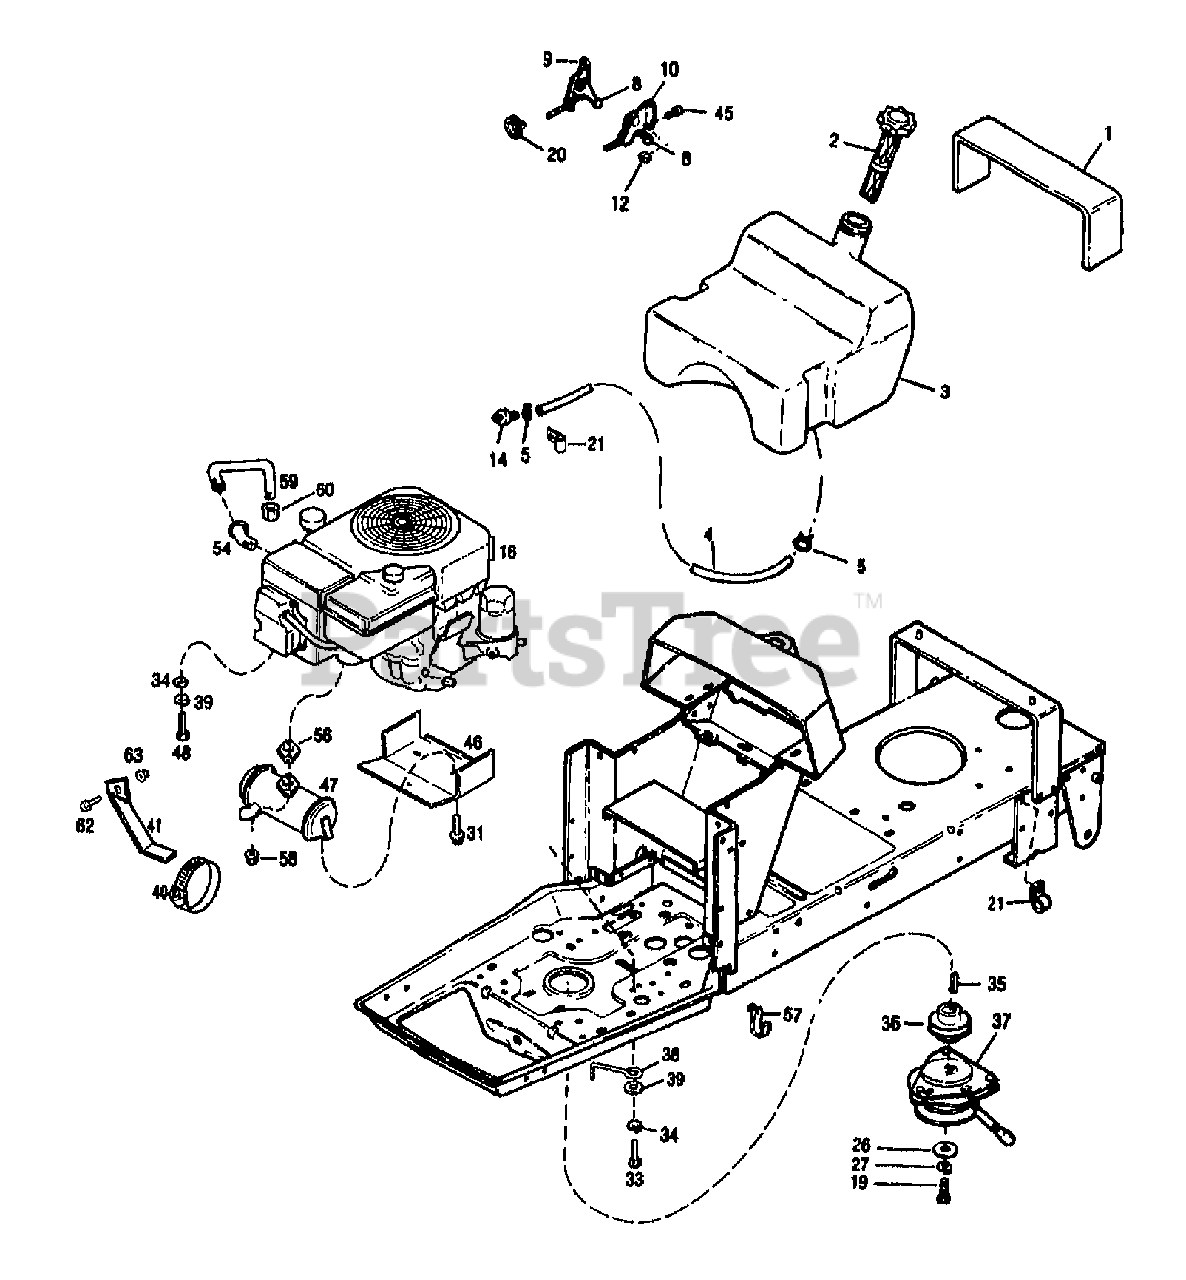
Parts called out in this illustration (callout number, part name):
1	PAD-FUEL TANK
2	CAP-GAS
3	TANK-FUEL
4	LINE-FUEL 52"
5	CLAMP-HOSE
8	KNOB
9	THROTTLE-CONTROL
10	C-CONTROL
12	NUT W/LKWASHER 10-24 ZP
14	FILTER-FUEL
16	ENGINE, KOHLER MODEL CV1259 (OHV) 12.5HP
19	SCR-HH M10X1.5X80
20	TIE-CABLE NYLON BLACK
21	CLIP-J
26	WASHER-SPEC 1.42X.468X.25 ZP
27	WASHER-LK .438 ZP
31	SCR-HFLK 1/4-20 X .375
33	SCR-HH M8-35
34	WASHER-LK .312 ZP
35	KEY-.25 SQ X 2.5
36	SHEAVE
37	CLUTCH-ELECTRIC
38	CLUTCH-RETAINER
39	WASHER-FLAT 5/16 SAE
40	CLAMP-WORM
41	BRKT-MUFFLER
46	SHIELD-HEAT
47	KIT-MUFFLER
48	BOLT-M8X25
54	ELBOW-45 DEGREES
56	GASKET
57	HANGER-CABLE
58	NUT
59	TUBE-OIL DRAIN
60	CAP-DRAIN TUBE
62	SCR-HH 1/4-20X.625
63	NUT-HF/LK 1/4-20 ZP
